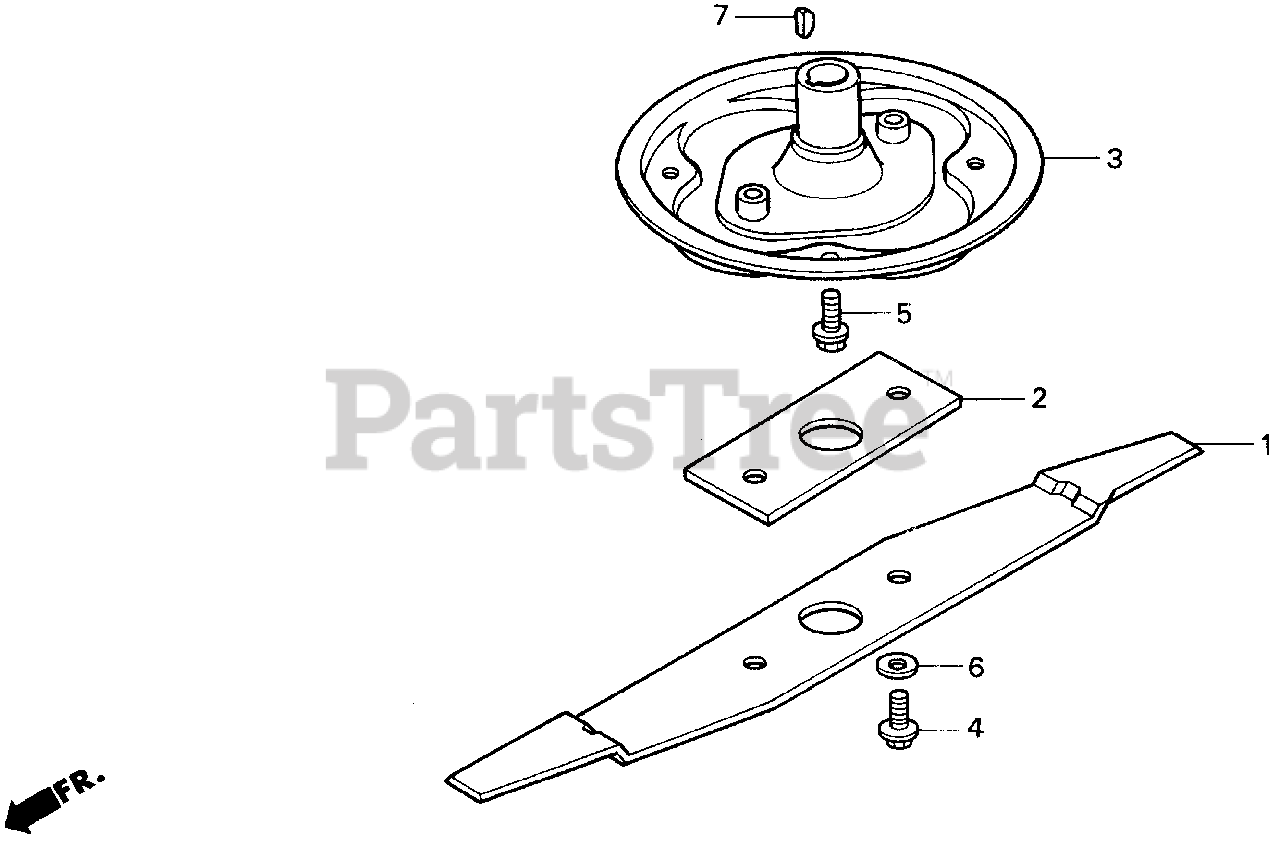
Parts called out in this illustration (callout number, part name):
1	BLADE, MULCHING (UPPER)
2	SPACER, BLADE
3	HOLDER, BLADE
4	BOLT, HEX. (10X25)
5	BOLT, HEX. (10X25)
6	WASHER, SPRING (10MM)
7	KEY, WOODRUFF (16X15)
NI	BLADE, MULCHING (LOWER)
